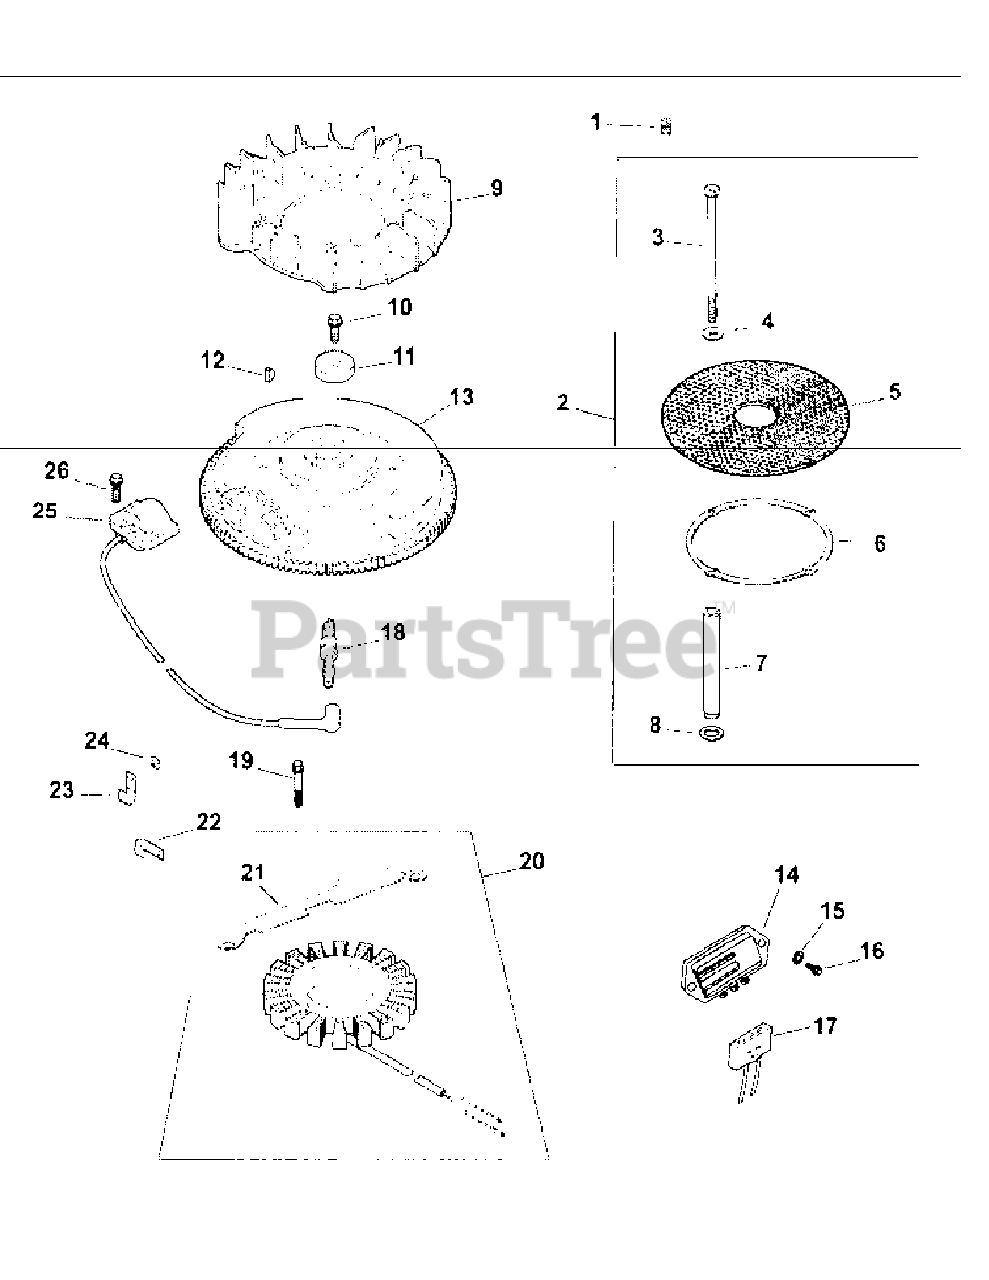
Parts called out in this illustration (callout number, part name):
2	Chopper Screen Kit
3	Hex Head Screw
4	Plain Washer
6	Support Ring
7	Grass Screen Spacer
8	Spring Washer
9	Fan
10	Hex Flange Screw
11	Plain Washer
14	Rectifier-Regulator
15	Plain Washer
16	Phillips Screw
18	Spark Plug
19	Hex Cap Screw
20	Stator Kit
21	Stator Wire Bracket
22	Cable Clip
24	Plain Washer
25	Ignition Coil
26	Hex Flange Screw
